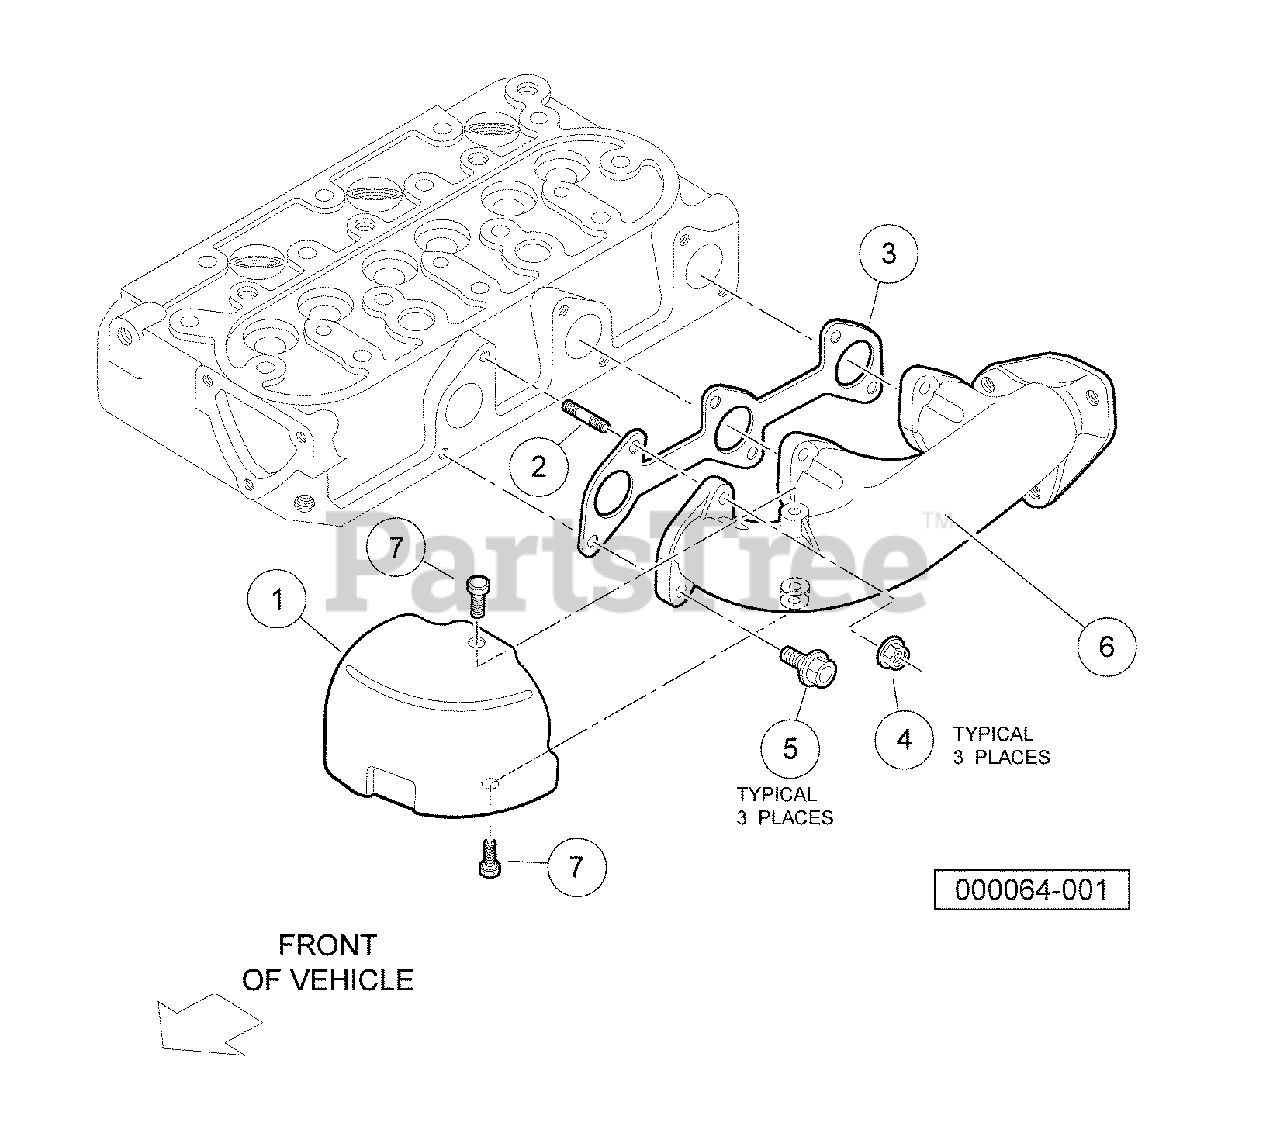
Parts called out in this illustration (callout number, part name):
1	Cover, Heat Proof
2	Stud, M6 X 26
3	Gasket, Ex-manifold
4	Nut, Flange, M6, Ubs
5	Bolt, Flange Head, M6 X 1 X 16
6	Manifold, Exhaust, D722
7	Bolt, D722, Exhst Manfld Cover
